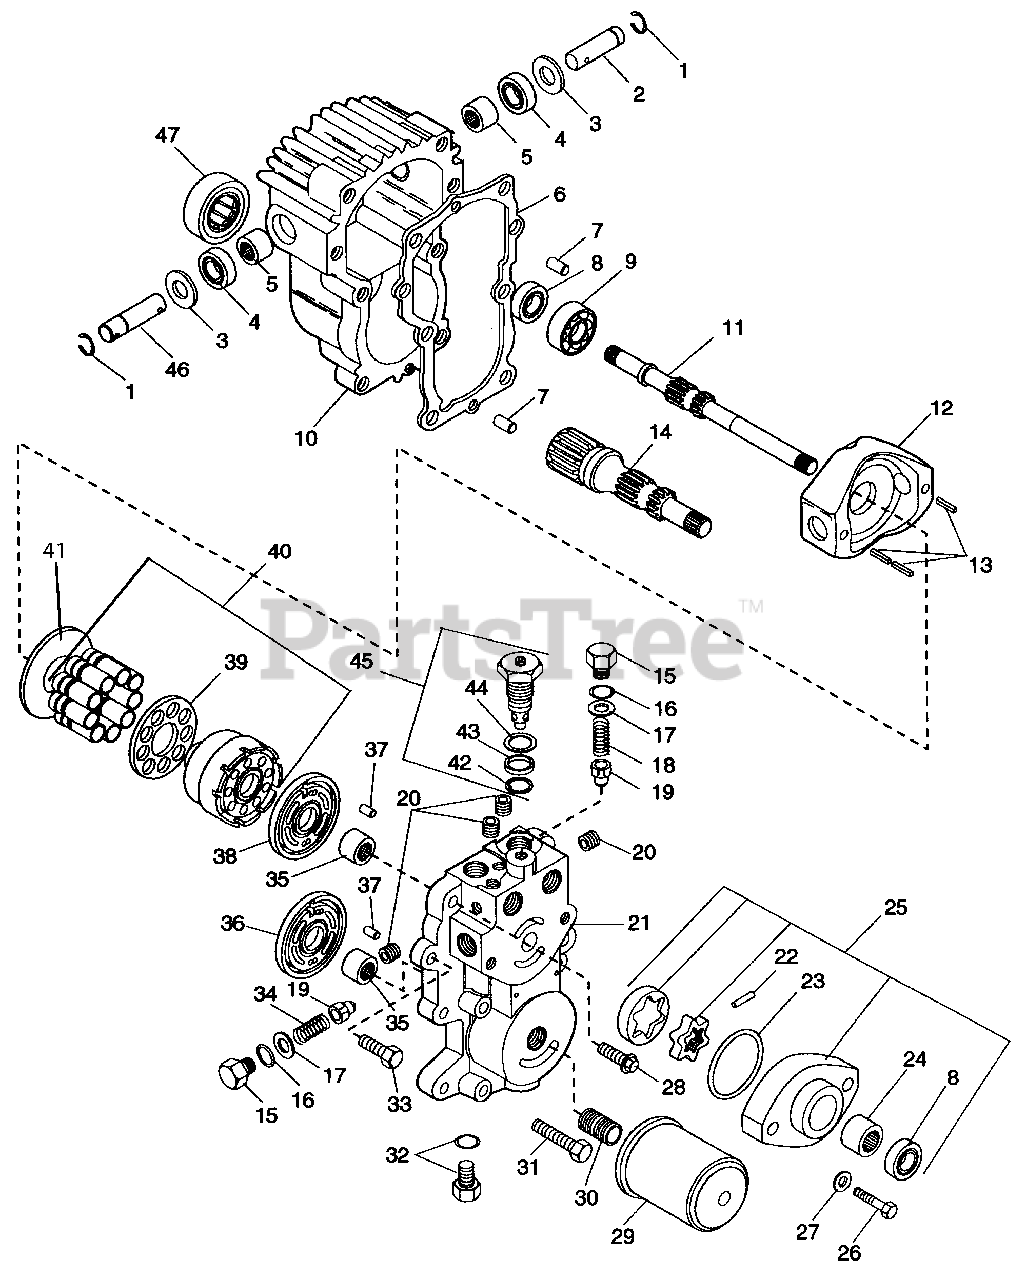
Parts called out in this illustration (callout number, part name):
1	RG-RTNG-EXT .688 X .042
2	TRUNNION SHAFT
3	WSHR-FL-STL .699 X 1.375 X .059
4	SEAL-LIP .625 X 1.187 X .187
5	JOURNAL BEARING
7	DOWEL PIN
8	SEAL .625 X 1.128 X .250
9	BRG-BALL 17MM X 40MM X 12MM
10	HOUSING ASSEMBLY KIT
11	SHAFT, PUMP
12	SWASHPLATE VARIABLE
13	PIN-ROLL .188 X .63
14	SHAFT, MOTOR
15	PLUG HEX HEAD
16	O-RING .414 X .562 X .072
17	SHIM PACKAGE
18	SG-COMP SUNSTRAND
19	RELIEF VALVE CONE
20	PIPE PLUG
21	CENTER SECTION
23	O-RING 2.364 X 2.504 X .072
24	BRG-NEEDLE .625 X .875 X .50
25	CHARGE PUMP ASSEMBLY KIT
26	BLT-HEX .44-14 X 2.00 GR 5
27	WSHR-FL-STL .469 X .719 X .108
28	SCR-12PN .38-16 X 1.25 GR 5
29	OIL FILTER
31	BLT-HEX .38-16 X 2.00 PL GR 5
32	THREADED PLUG
33	BLT-HEX .38-16 X 1.50 PL GR 5
34	SG-COMP SUNSTRAND
35	BRG-NEEDLE 17MM X .938 X .62
36	MOTOR VALVE PLATE
37	DOWEL PIN
38	VALVE PLATE
39	SLIPPER RETAINER
40	CYLINDER BLOCK KIT
41	THRUST PLATE
42	O-RING .614 X .750 X .070
43	O-RING .614 X .750 X .046
44	O-RING .770 X .968 X .097
45	CHECK VALVE ASSEMBLY KIT
46	TRUNNION SHAFT
47	BRG-ROLLER 1.27 X 2.05 X 15MM
